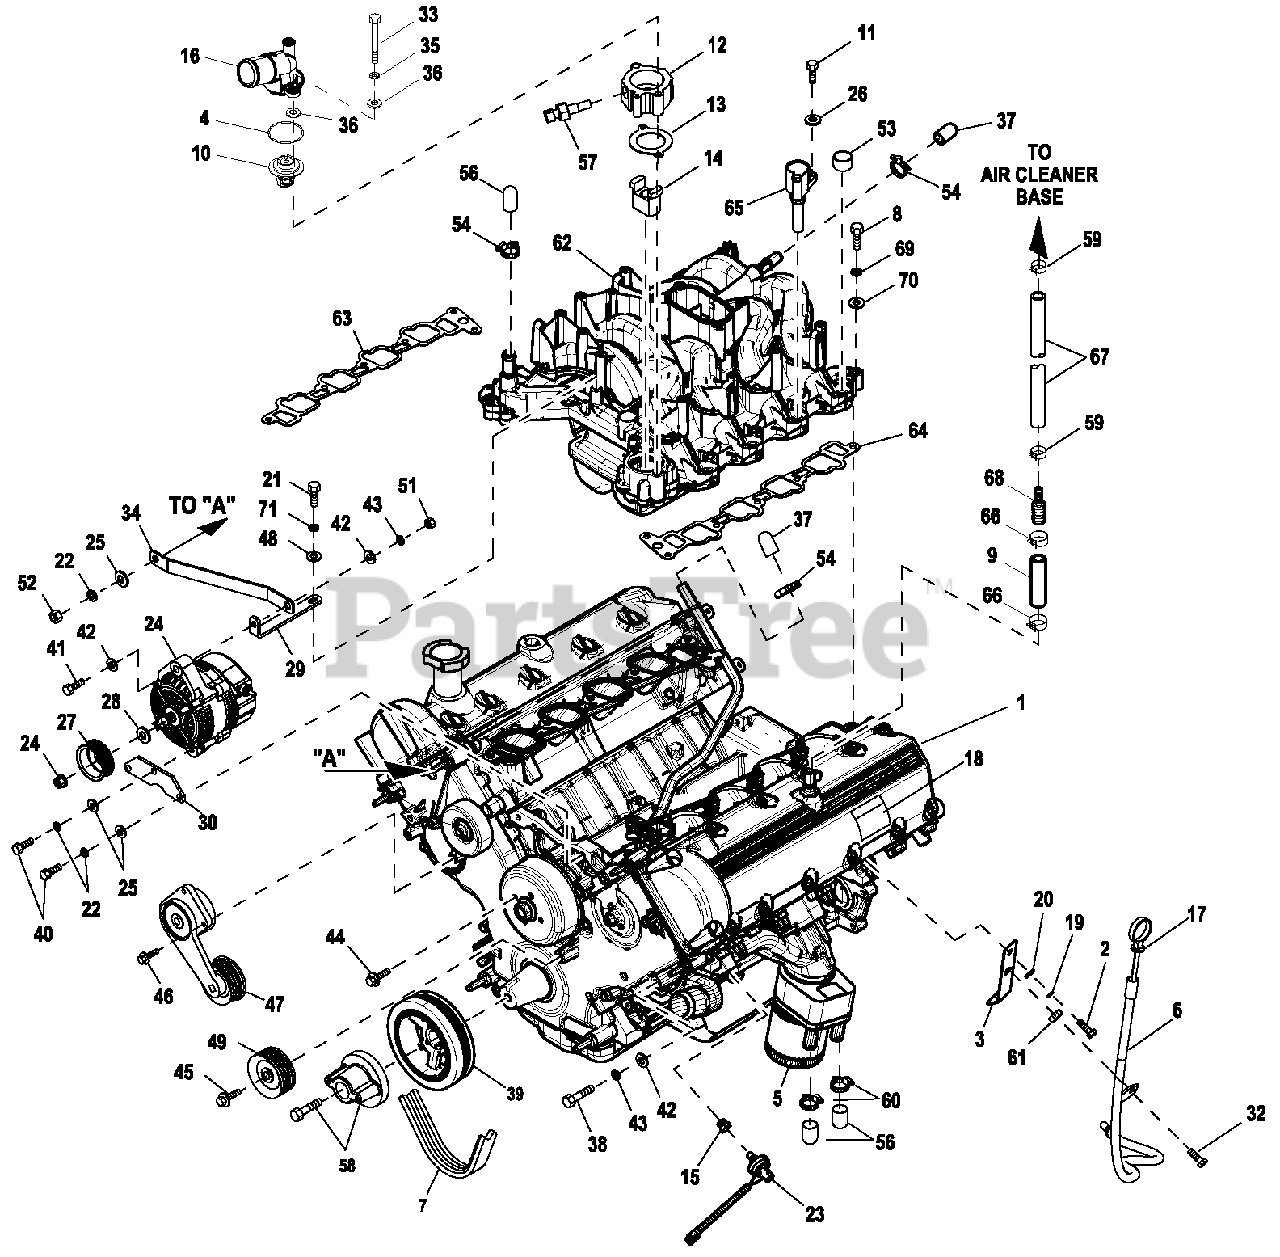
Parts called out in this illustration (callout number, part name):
1	5.4L G3 - LONG BLOCK
2	SCREW HHC M6-1.0X20 C8.8
3	BRACKET DIPSTICK TUBE
4	GASKET THERMOSTAT HOUSING
5	OIL FILTER V-10 ENGINE
6	T UBE DIPSTICK
7	BELT SERPENTINE 68.3"
8	SCREW HHC M8-1.25X50 C8.8
9	HOSE COOL 5/8"ID 250#WP (2" LG)
10	5.4L G3 - THERMOSTAT
11	SCREW HHC M5-0.8 X 25 C8.8 BLK
12	ADAPTER T HERMOSTAT 4.6L G3
13	GASKET T HERMOSTAT 4.2L
14	SPACER COOLANT BYPASS
15	BSHG RDCR HEX 1/4 TO 1/8
16	5.4L G3 - THERMOSTAT OUTLET
17	DIPSTICK
18	DECAL EPA STATIONARY EMERGENCY
19	WASHER LOCK M6-1/4
20	WASHER FLAT 1/4-M6 ZINC
21	SCREW HHC M6-1.0X20 C8.8
22	WASHER LOCK M8-5/16
23	HARN LOW OIL PRESS SWITCH ASSY
24	ALTERNATOR DC W/OUT PULLEY
25	WASHER FLAT 5/16 ZINC
26	WASHER FLAT M5
27	PULLEY 160 OD DC ALT ERNATOR (3600 RPM)
28	SPACER DC ALTERNATOR PULLEY
29	BRKT DC ALT ERNAT OR UPPER
30	BRKT DC ALT ERNAT OR LOWER
32	SCREW HWHT FM6-1.0X16
33	SCREW HHC M8-1.25X 140 G8.8
34	BRACKET DC ALT STABILIZER
35	WASHER LOCK M8-5/16
36	WASHER FLAT 5/16-M8ZINC
37	CAP ANTIFREEZE 5/8"ID X 1.2"LG
38	SCREW HHC M10-1.5X60 C8.8
39	REWORK HARMONIC BALANCER 5.4L
40	SCREW HHC M8-1.25X20 G8.8
41	SCREW HHC M10-1.5 X 45 G8.8 FT
42	WASHER FLAT 3/8-M10ZINC
43	WASHER LOCK M10
44	SCREW WP PULLEY M8-1.25 X 19
45	BOLT HEX FL HD M8-1.25 X 28
46	BOLT HEX FL HD M8-1.25 X 31
47	T ENSIONER ENG. AUTOMATIC BELT
48	WASHER FLAT 1/4-M6 ZINC
49	PULLEY GROOVED ENGINE IDLER
51	NUTHEXM10-1.5 G8 YELCHR
52	NUT HEXM8-1.25G8 YELCHR
53	PLUG EXPANSION 14 OD
54	CLAMP HOSE #10.56-1.06
57	TEMPERATURE SENDER, DELPHI
58	COUPLING FLEX HUB MACH
59	CLAMP HOSE BAND .63
60	CLAMP HOSE #12. 50-1. 25
61	NUT HEX M8-1.25 G8 CLEAR ZIN
62	5 . 4L G3 - INTAKE MANIFOLD
63	5 . 4L G3 - INTAKE GASKET RH
64	5 . 4L G3 - INTAKE GASKET LH
65	COIL & BOOT ASY-IGNITION
66	CLAMP HOSE BAND . 88"
67	HOSE 3/8 ID SINGLE BRAID (14 .75" LG)
68	HOSE BARB REDUCER 5/8"-3/8"ID
69	WASHER LOCK M8-5/16
70	WASHER FLAT 5/16 ZINC
71	WASHER LOCK M6-1/4
